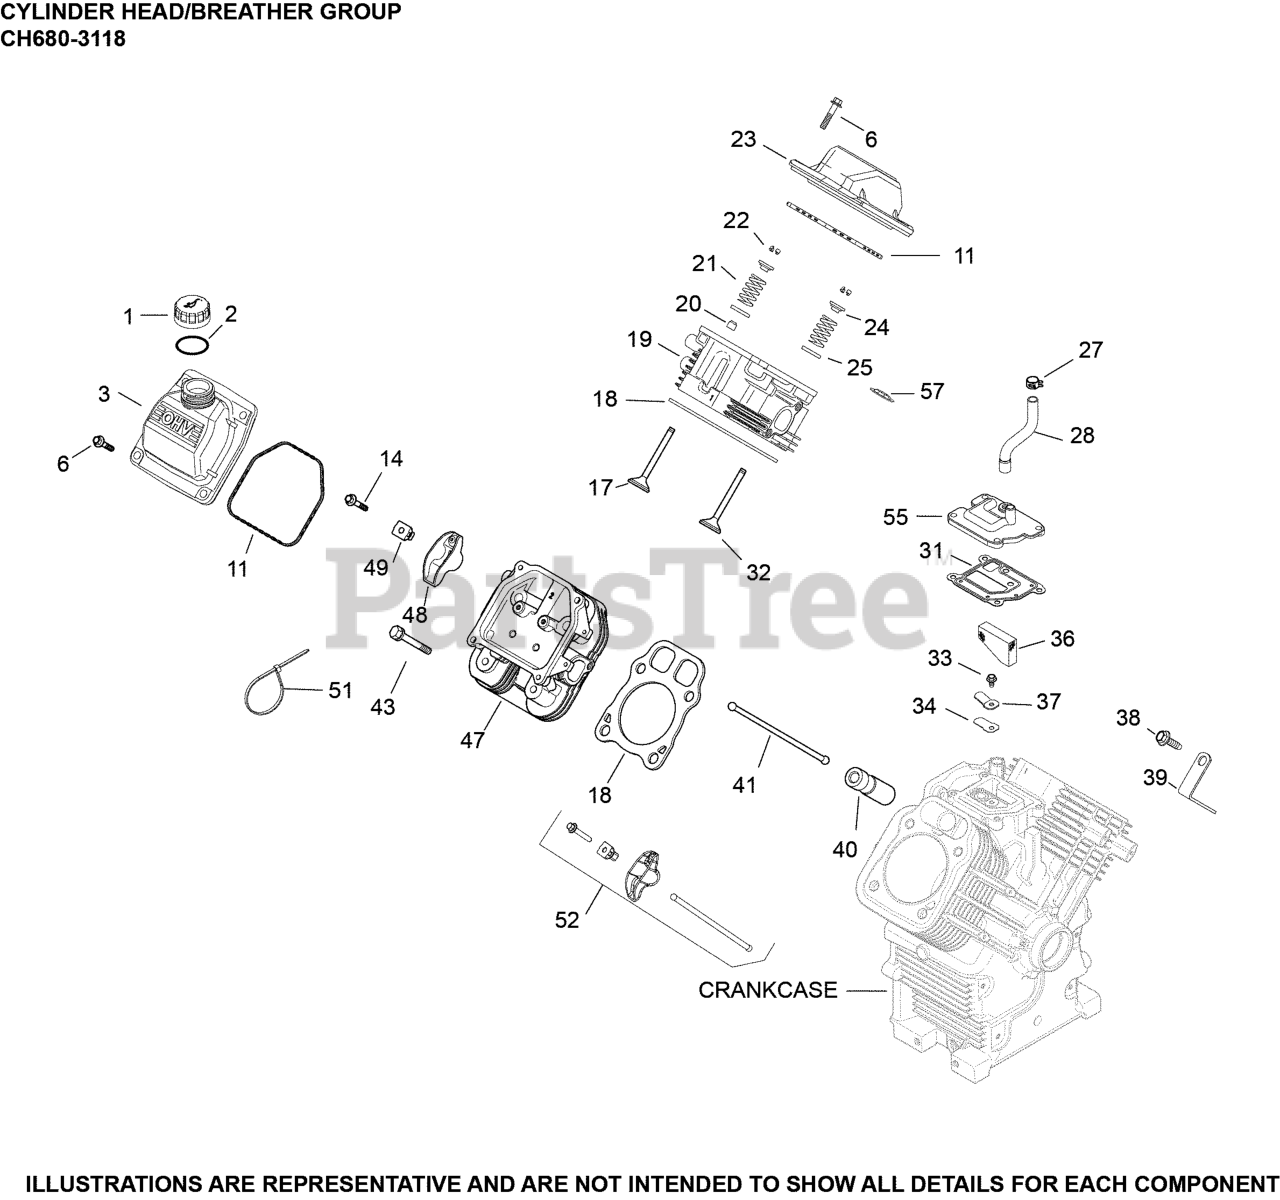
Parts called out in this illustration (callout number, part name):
1	KIT, OIL FILL CAP (BLACK)
2	O-RING, DIPSTICK
3	KIT, VALVE COVER-OIL FILL
6	SCREW, FLG M6X1.0X30
11	O-RING (YELLOW), VALVE COVER
14	SCREW, FLG M6X1.0X34
17	VALVE, EXHAUST (STD) - USE 32 016 01-S
17	VALVE, EXHAUST (.25)
18	KIT, GSKT CYL HD (C22-23 674CC)
19	HEAD ASSEMBLY, CYLINDER (#1) USE 24 318 173-S
20	SEAL, VALVE BAND
21	SPRING, VALVE
22	KIT, RETAINER
23	KIT, VALVE COVER-PLAIN (PLASTIC)
24	CAP, VALVE SPRING
25	RETAINER, SPRING
27	CLAMP SPRING HOSE
28	HOSE, BREATHER
31	GASKET, BREATHER
32	VALVE, INTAKE (STD)
32	VALVE, INTAKE (.25)
33	SCREW, FLG THD FRM M5X.8X10
34	REED, BREATHER
36	FILTER, BREATHER
37	RETAINER, REED
38	SCREW, THREAD FORMING
39	STRAP, LIFT
40	LIFTER, VALVE HYDRAULIC - (#2535111S)
41	ROD, PUSH
43	SCREW, FLG M10X1.5X90
47	HEAD ASSEMBLY, CYLINDER (#2) USE 24 318 174-S
48	ARM, ROCKER
49	PIVOT, ROCKER ARM
52	KIT, VALVE TRAIN
55	COVER, BREATHER
57	RETAINER, VALVE GUIDE (KM)
